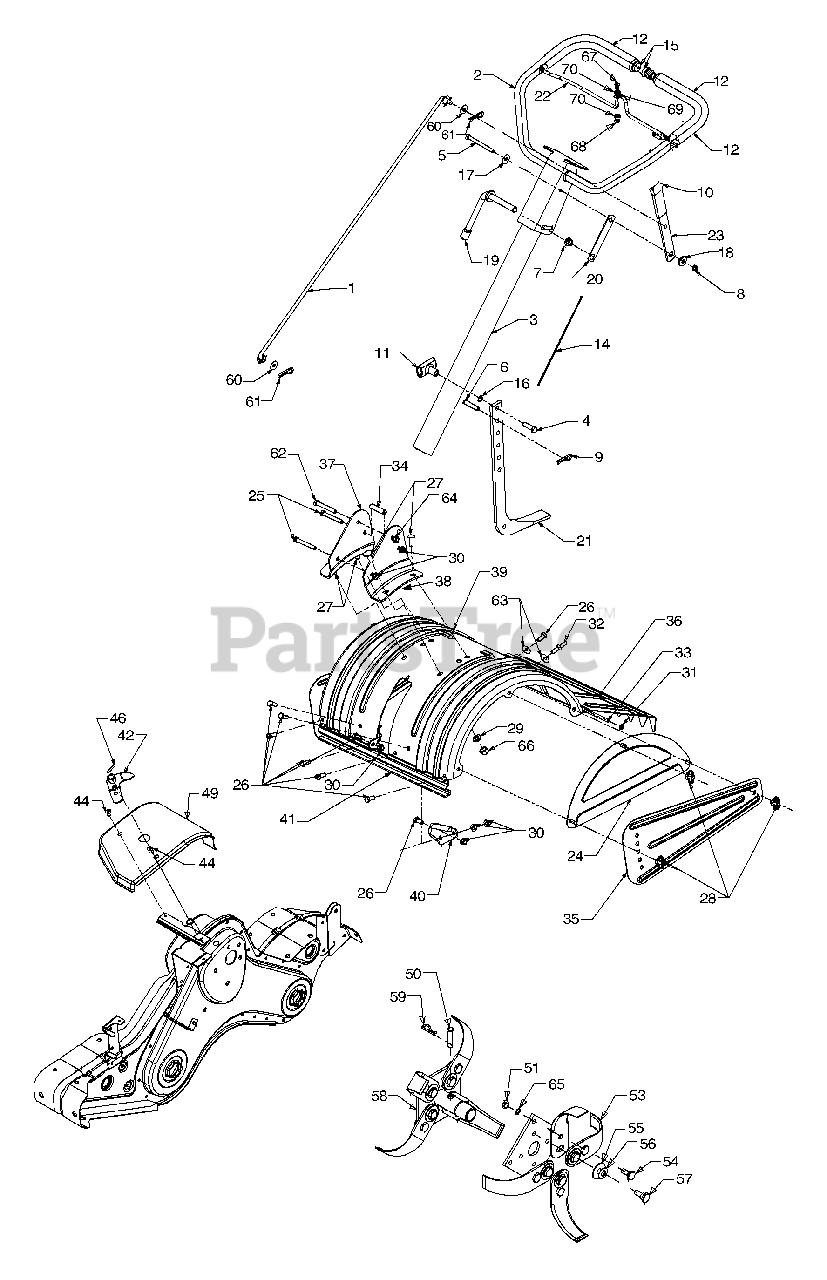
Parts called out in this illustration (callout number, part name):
1	Shift Rod
4	Hex Screw 3/8-16 x 1.25
5	Hex Screw 5/16-18 x 3.25
6	Clevis Pin 3/8-1.62
7	Flange Lock Nut 3/8-24
8	Hex Lock Nut 5/16-18
9	Cotter Pin
11	T-Knob
12	Foam Grip
14	Cable Tie
16	Flat Washer 3/8 x .620 x .033
17	Bell Wash. .340 I.D. x .872 O.D.
18	Shoulder Spacer
19	Handle Adjustment Crank
20	Hex Nut Ret. Bracket
21	Depth Stake
22	Bail Clutch
25	Hex Cap Screw 5/16-18 x 2.75
26	Hex Cap Screw 5/16-18 x .750
27	Carriage Bolt 3/8-16 x 1.0
28	Wing Nut
29	Lock Washer 3/8
30	Flange Nut 5/16-18
31	Cap Nut
32	Hex Screw 5/16-18 x .75" Lg.
34	Spacer .435 O.D. x .322 I.D.
40	Tine Shield Brkt.
41	Shoulder Spacer Brkt.
42	Shift Crank Ass'y
44	Screw 1/4-14 x .625
46	Spiral Pin 3/16 x 1.00
51	Hex Nut 3/8-24 Thd.
53	13" Dia. Articulating Tine
54	Shld. Bolt 1/2" DIa. x .175
55	Fl-Wash. .51" I.D. x 1.50"
56	Bell-Wash. .515" I.D. x 1.14"
57	Shld. Bolt 1/2" Dia x .320
58	Tine Adapter Ass'y 18"
59	Internal Cotter Pin
60	Rubber Washer
61	Cotter Pin
62	Hex Screw 3/8-16 x 2.75" Lg.
63	Flat Washer
64	Flange Nut .344 I.D. x .62 O.D.
65	Lock Washer
66	Hex Nut 3/8-16
67	Truss Screw 1/4-20 x .65
68	Hex Lock Nut 1/4-20 Gr. 8
69	Battery Hose Clamp 5/16
70	Flat Washer .260 x .720 x .060
